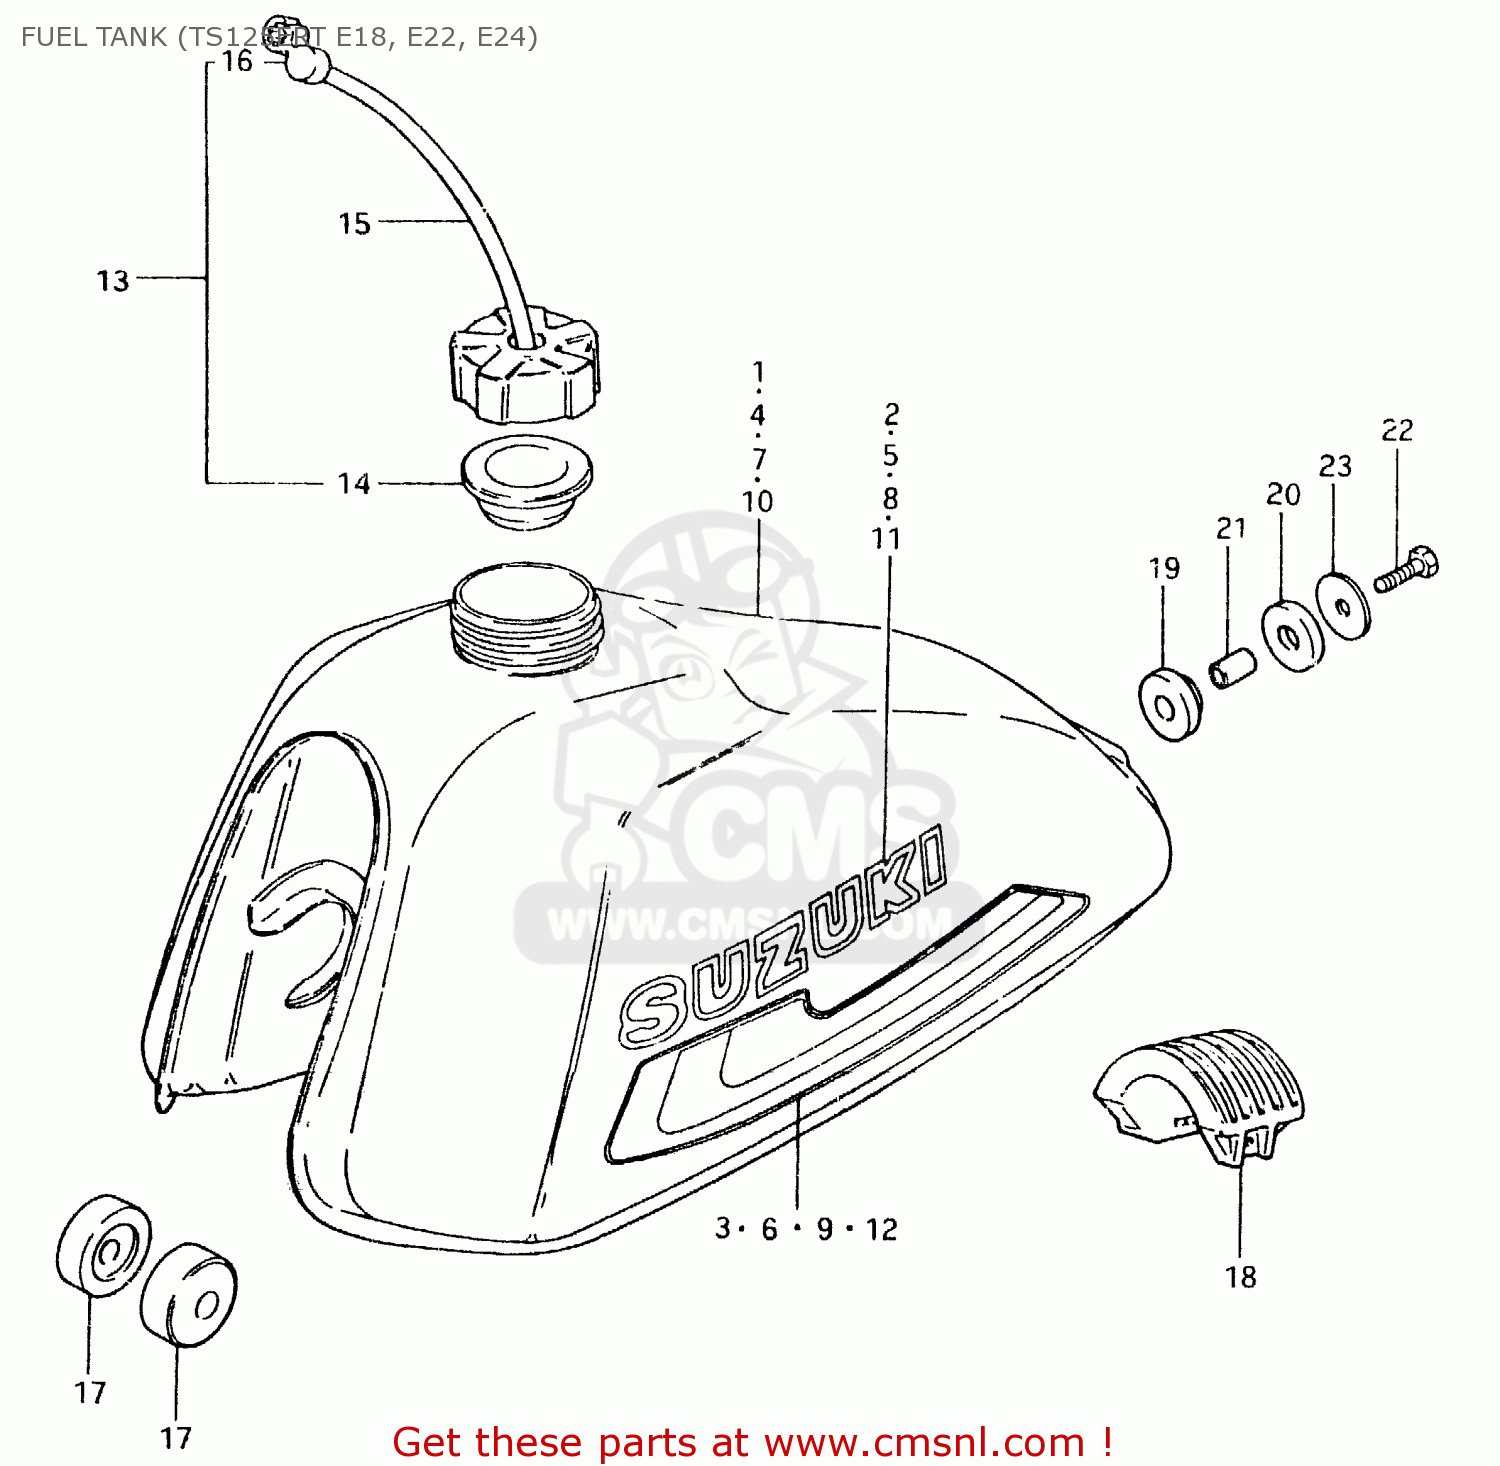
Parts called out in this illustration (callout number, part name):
1	TANK, FUEL (BLACK)
2	EMBLEM,FUEL TANK(WHITE)
3	TAPE SET
4	TANK, FUEL (YELLOW)
5	EMBLEM
6	TAPE SET
7	TANK, FUEL (RED)
8	EMBLEM,FUEL TANK(WHITE)
9	TAPE SET
10	TANK, FUEL (WHITE)
11	EMBLEM
12	TAPE SET
13	CAP SET,FUEL TANK
14	GASKET,FUEL TANK CAP (NAS)
15	HOSE
16	CLAMP,FUEL TANK BREATHER HOSE
17	CUSHION
18	CUSHION,FUEL TANK
19	CUSHION
20	CUSHION
21	SPACER(8.5X12X19)
22	BOLT (8X30)
23	WASHER (8.5X29X1.6)
